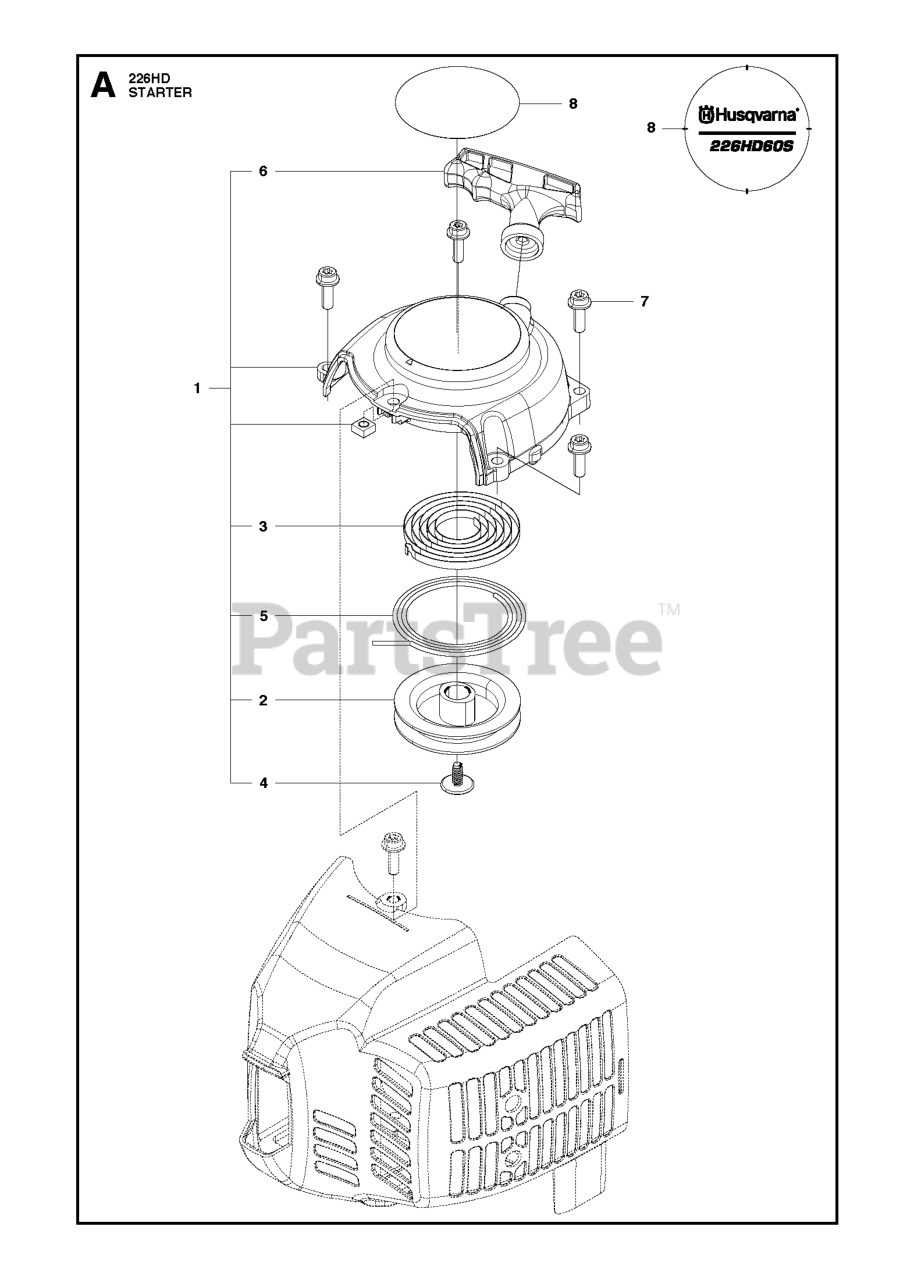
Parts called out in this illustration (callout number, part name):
1	RECOIL ASSY
4	SCREW
8	LABEL, RECOIL
